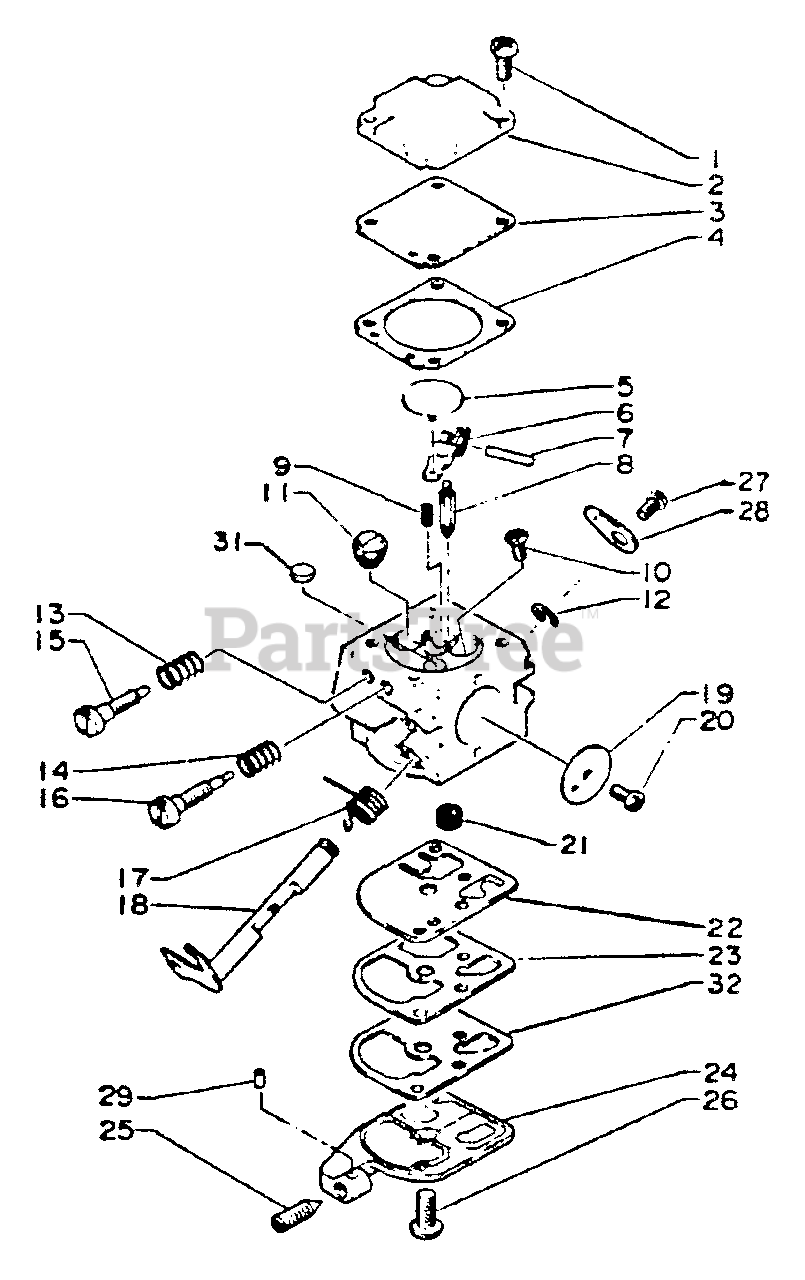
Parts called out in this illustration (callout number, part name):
1	SCREW
2	COVER, DIAPHRAGM
3	DIAPHRAGM
4	GASKET, METERING
5	DISK
6	LEVER, METERING
7	PIN, METERING LEVER
9	SPRING, METERING LEVER
14	SPRING, METERING LEVER
15	NEEDLE, HIGH SPEED
16	NEEDLE, IDLE
17	SPRING, THROTTLE RETURN
18	SHAFT, THROTTLE
19	VALVE, THROTTLE
20	SCREW
21	STRAINER
24	BASE, PUMP
25	SCREW, IDLE ADJUST
28	LEVER, THROTTLE
29	PIECE, FRICTION
31	PLUG, WELCH
32	DIAPHRAGM, SURGE
